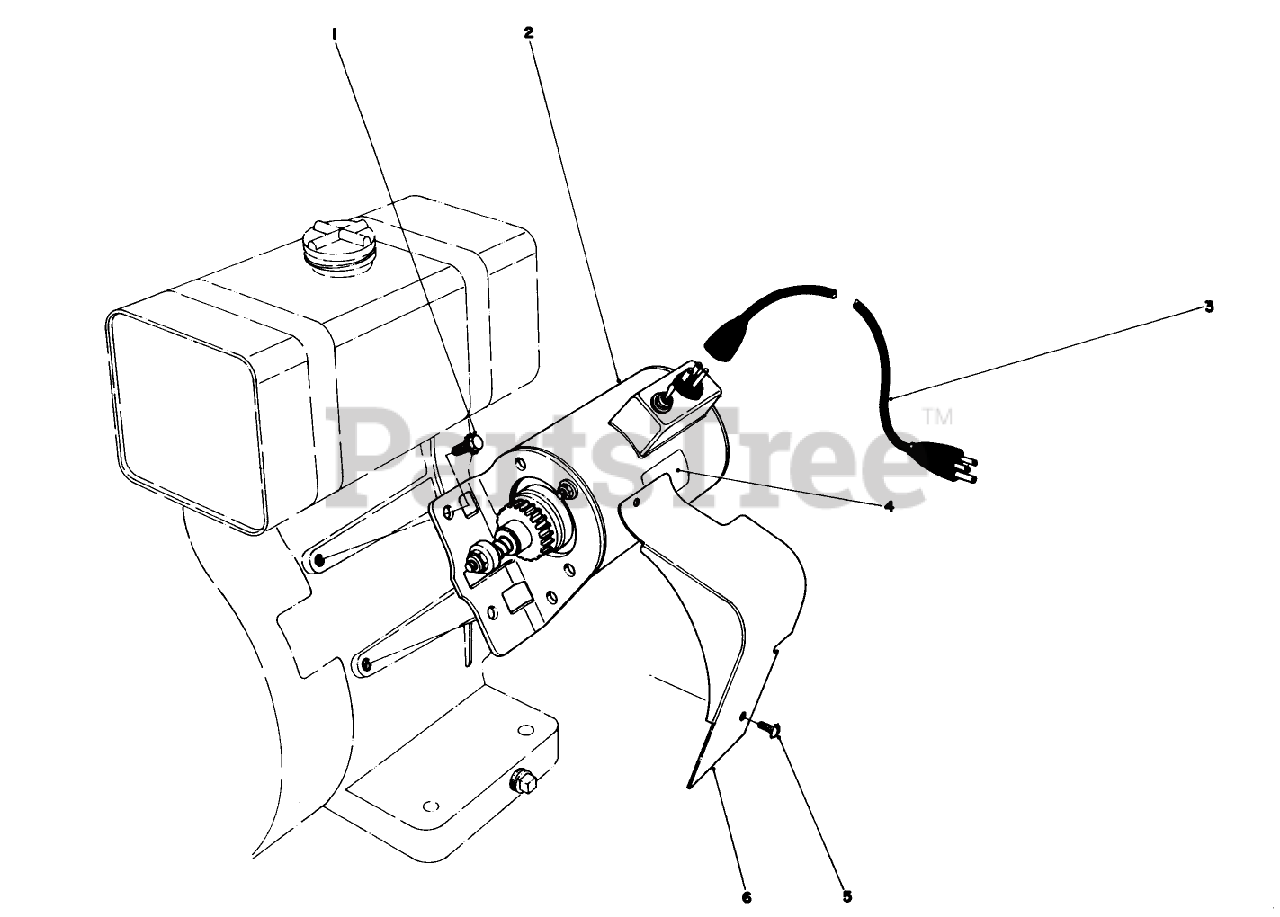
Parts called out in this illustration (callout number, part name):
1	5/16-18X3/4 HX HD SEM
2	Starter Motor Assembly
3	TECUMSEH 7641
4	Decal
6	Starter Pinion Cover
